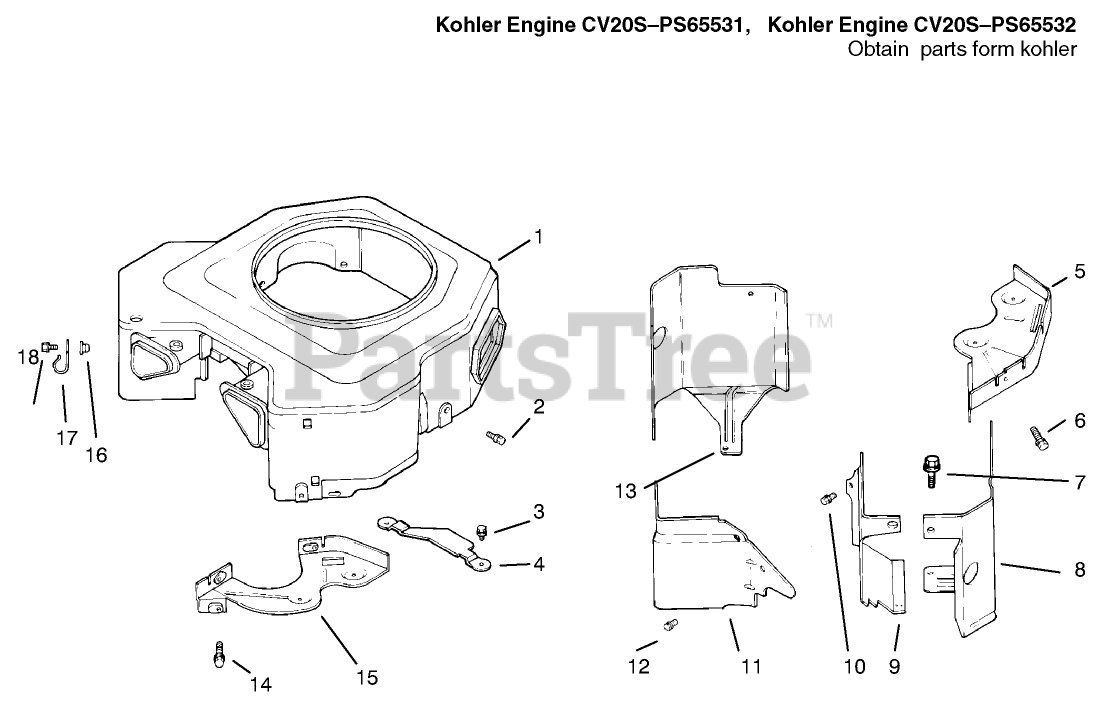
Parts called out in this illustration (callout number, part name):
1	Housing-Blower ASM (Only C)n: 72103, 72083)
4	Guard-Flywheel (Only On: 72103, 72083)
5	Plate-Backing #2 side
8	Baffle Cylinder #2 Side
9	Baffle-Valley #1 Side (Only On: 72103)
11	Baffle-Valley #2 Side (Only On: 72103, 72083)
13	Baffle-Cylinder #1 Side (Only On: 72103)
15	Plate-Backing #1 Side (Only On: 72103, 72083)
17	Clip-Cable (Only On: 72103)
